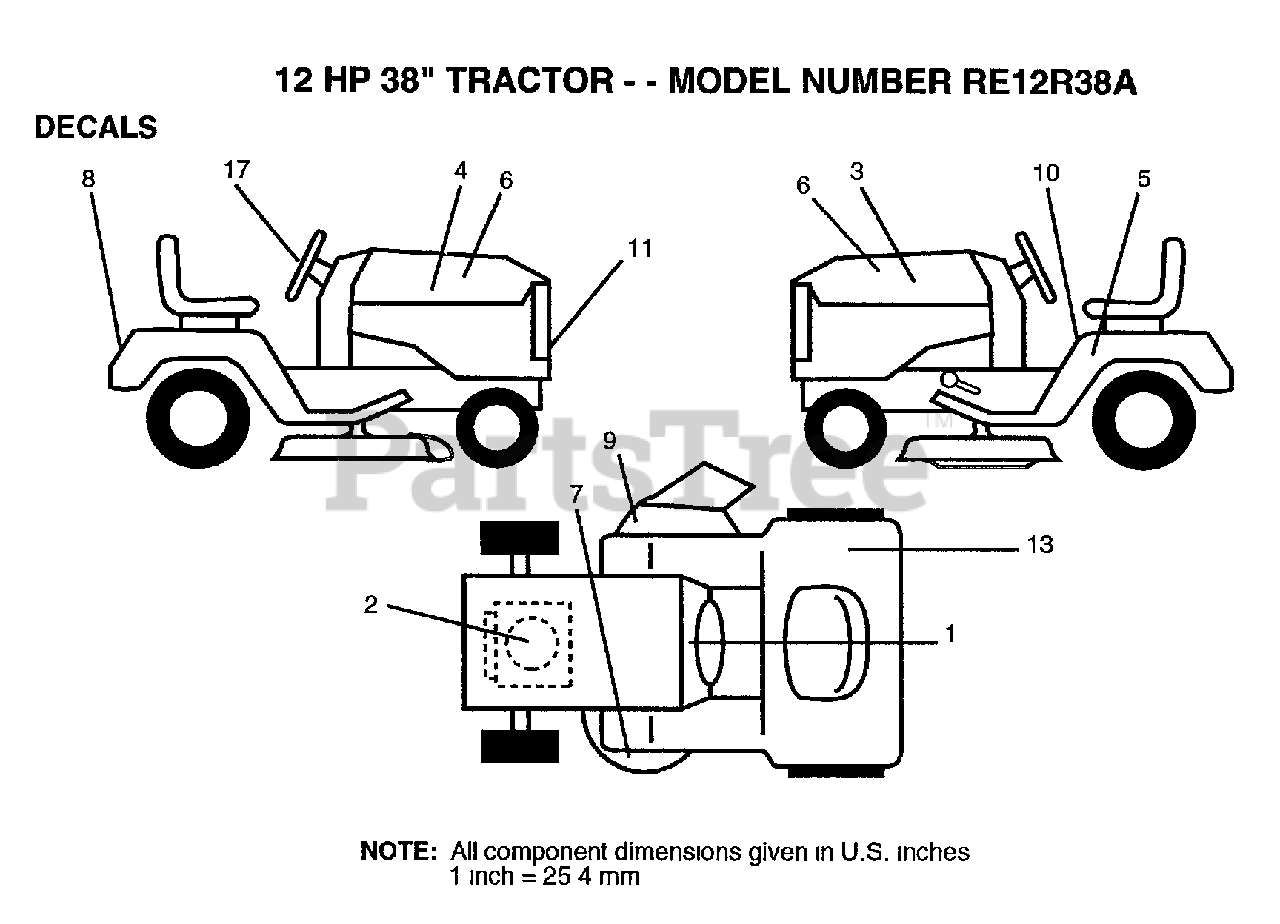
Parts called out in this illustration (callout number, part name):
5	IND HGT DECK DECA
6	"DECAL,HOOD"
8	FENDER DECAL
9	DECAL WARNING
10	DECAL CAUTION
11	GRILL DECAL
17	"DECAL,STR WHL"
